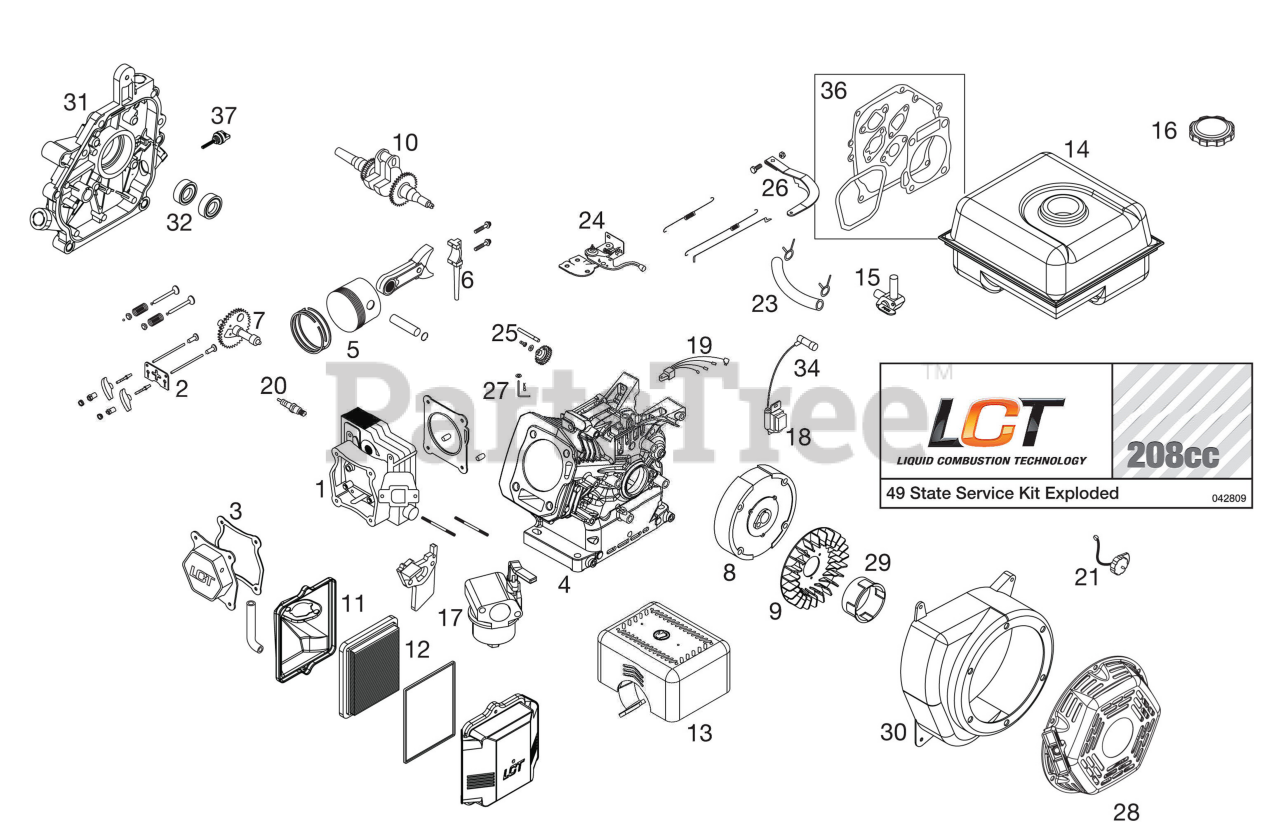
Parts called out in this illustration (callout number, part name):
1	CYLINDER HEAD SERVICE KIT
2	PUSH ROD SERVICE KIT
3	VALVE COVER SERVICE KIT
4	CYLINDER SERVICE KIT
5	PISTON SERVICE KIT
6	CONNECTING ROD SERVICE KIT
7	CAMSHAFT SERVICE KIT
8	FLYWHEEL SERVICE KIT
9	COOLING FAN SERVICE KIT
10	CRANKSHAFT SERVICE KIT
11	49 STATE AIR FILTER ASSEMBLY SERVICE KIT
12	PAPER FILTER SERVICE KIT
13	49 STATE MUFFLER ASSEMBLY SERVICE KIT
14	49 STATE FUEL TANK ASSEMBLY SERVICE KIT
15	FUEL TANK PETCOCK SERVICE KIT
16	FUEL CAP KIT
17	CARBURETOR SERVICE KIT
18	IGNITION COIL SERVICE KIT
19	IGNITION MODULE SERVICE KIT
20	SPARK PLUG SERVICE KIT
21	ENGINE ON/OFF SWITCH SERVICE
23	FUEL HOSE SERVICE KIT
24	THROTTLE CONTROL SERVICE KIT
25	GOVERNOR GEAR SERVICE KIT
26	GOVERNOR ARM SERVICE KIT
27	GOVERNOR CRANK SERVICE KIT
28	RECOIL STARTER SERVICE KIT
29	STARTER CUP SERVICE KIT
30	BLOWER HOUSING SERVICE KIT
31	PTO COVER SERVICE KIT
32	SEAL SERVICE KIT
34	SPARK PLUG BOOT SERVICE KIT
36	GASKET SERVICE KIT
37	OIL DIPSTICK SERVICE KIT
